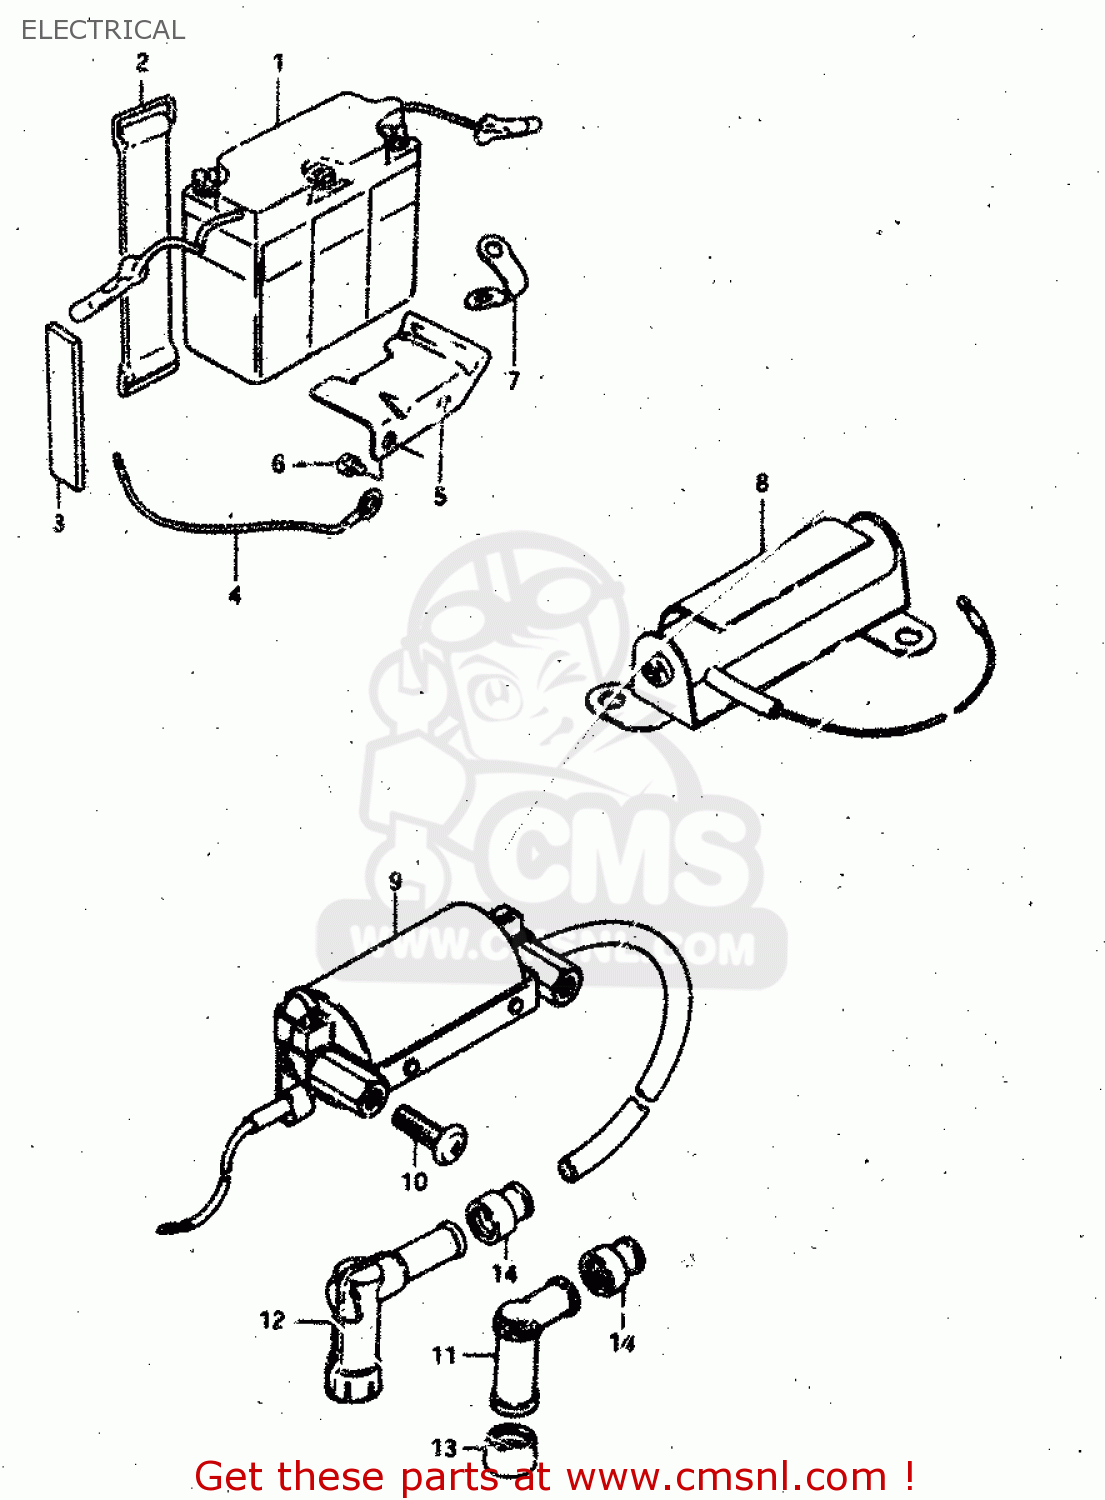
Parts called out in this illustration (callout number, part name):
1	BATTERY(6N4B-2A,6V4.2AH)
2	BAND
3	PROTECTOR,20X9
4	LEAD WIRE
5	HOLDER, BATTERY
6	BOLT
7	CLAMP
8	RESISTOR ASSY,LAMP
9	COIL ASSY, IGNITION
10	SCREW
11	CAP ASSY,SPARK PLUG
12	CAP,SPARK PLUG
13	SEAL, SPARK PLUG
14	SEAL,SPARK PLU
